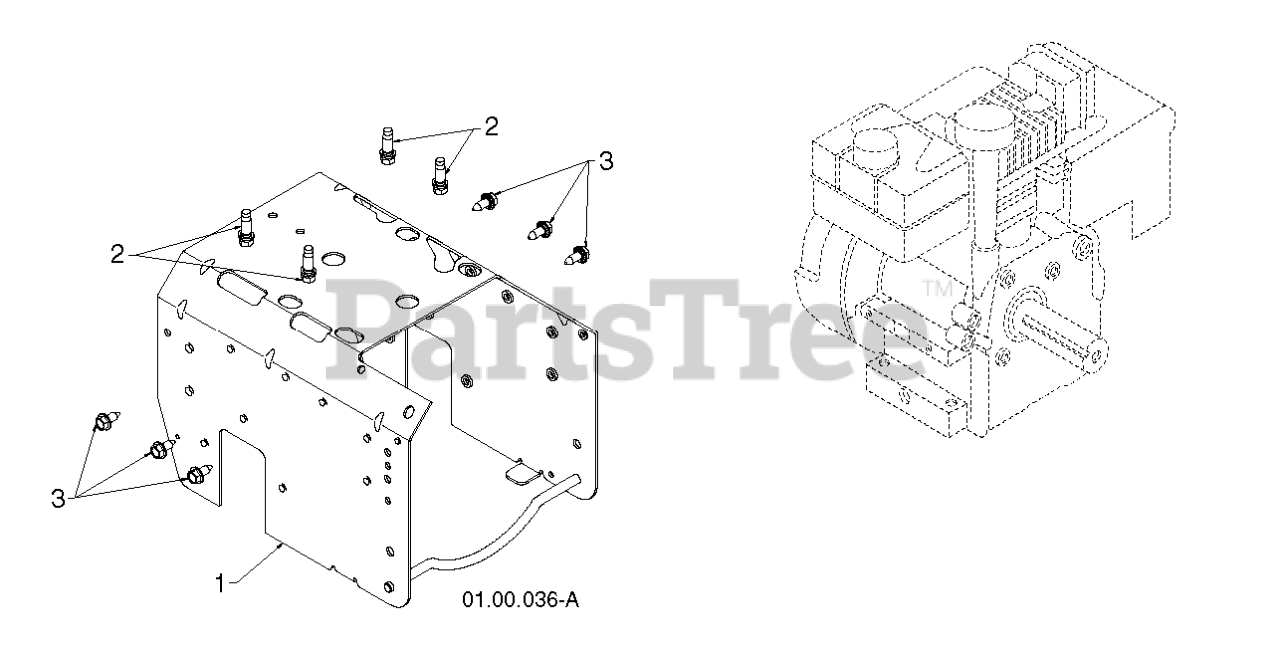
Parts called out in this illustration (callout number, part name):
1	FRAME.WELD.HYDRO.668.PNT
2	BOLT 3/8-16X1-1/8
3	BOLT.HEX.HD.WASHER.5/16-18X.75
